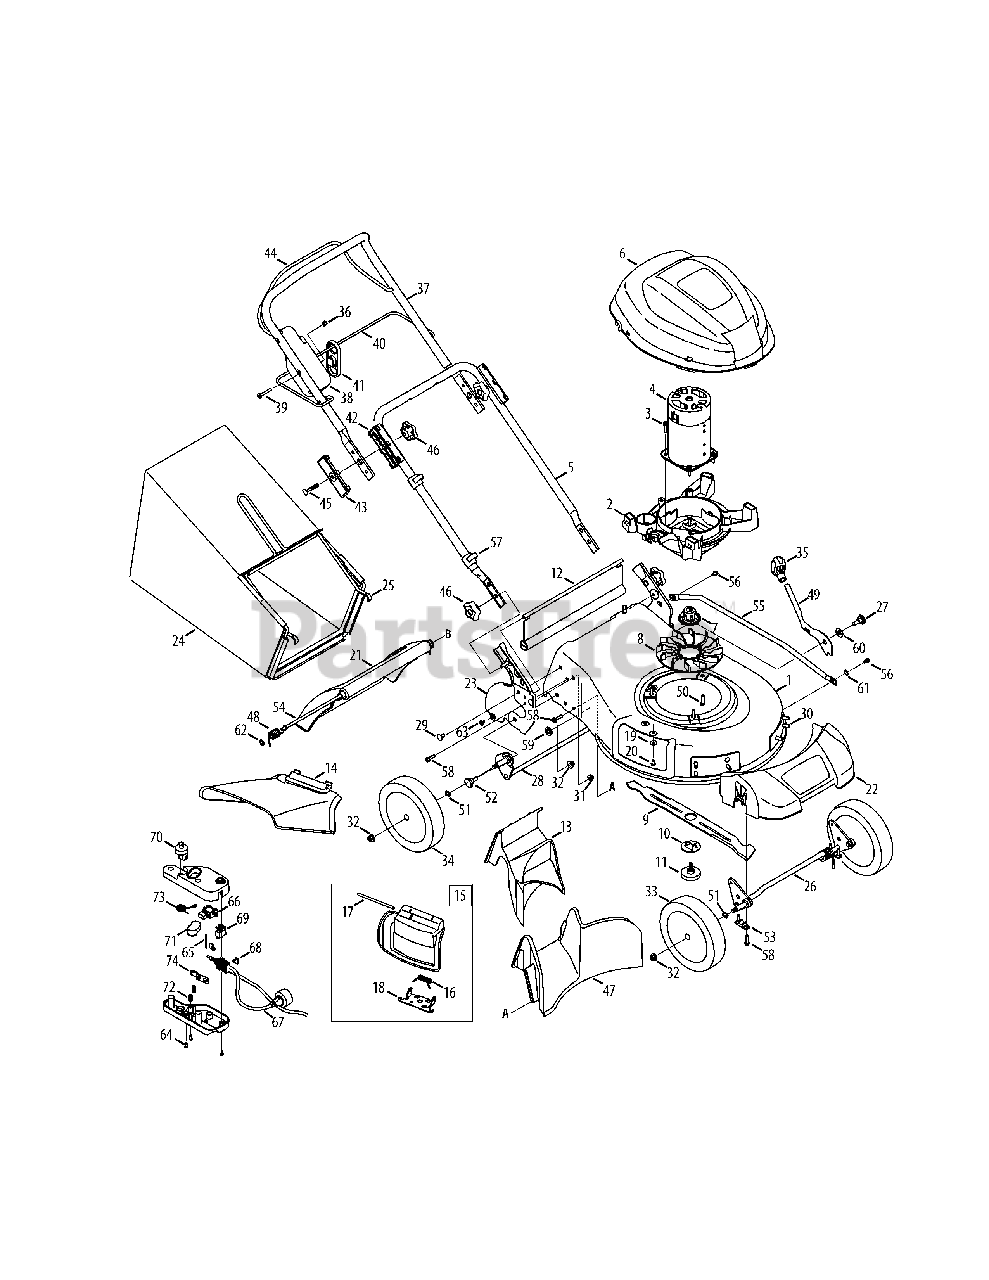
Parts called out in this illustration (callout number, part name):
2	Motor Bracket
3	Screw, 1/4-15 x .750
4	Electric Motor, 120V
6	Motor Shroud
8	Electric Fan
9	Mulching Blade
10	Blade Locking Plate
11	Blade Bolt Assembly
12	Trail Shield
13	Rear Mulch Plug
14	Side Discharge Chute
15	Mulch Plug (Incl. 16-18)
16	Torsion Spring
18	Chute Deflector Adapter
19	Beleville Washer
22	Front Cover
23	Handle Bracket - RH
23	Handle Bracket - LH
25	Grass Bag Frame
26	Front Bracket Assembly
27	Screw, Shoulder, .50 x .66
28	Rear Bracket Assembly
29	Screw, 5/16-18 x .625
30	Hi-lo Screw, 5/16-14 x .750
31	Nut, Flange Lock, 5/16-18
32	Nut, Flange Lock, 3/8-16
33	Front Wheel
34	Rear Wheel
36	Nut, Hex Lock, 1/4-20
37	Upper Handle
38	Motor/Blade Control
39	Screw, Flat, 1/4-20 x 1.75
41	Cord Retainer
42	Lower Handle Insulator
43	Upper Handle Insulator
44	Motor/Blade Control Handle
45	Bolt Carriage, 5/16-18 x 2.50
47	Rear Baffle
48	Door Torsion Spring - RH
48	Door Torsion Spring - LH
49	Spring Lever
50	Screw, 5/16-12 x .750
51	Washer, Wave, .510 x .750 x .017
52	Screw, Shoulder, .500 Dia. X .434
53	Bushing, Lock, .505 Dia. X .62
54	Rear Door Pivot Rod
55	Cross Bracket
56	Screw, Shldr., 1/4-20 x .50
57	Cable Guide
58	Screw, 1/4-15 x 1.000
59	Spacer, .515 x 1.00 x .310 Lg.
60	Washer, Bell, .510 x 1.14 x .040
61	Washer, Wave, .390 x .825 x .016
62	Nut, Speed
63	Screw, #10-16 x .500
64	Screw, 10-9 x .50
65	Switch Pivot Shaft
67	Wiring Harness
68	Jumper Wire
69	Circuit Breaker
70	Bail Lock Clip
71	Bail Lock Button
72	Compression Spring, .260 x .687
73	Torsion Spring
74	Switchbox Lever
